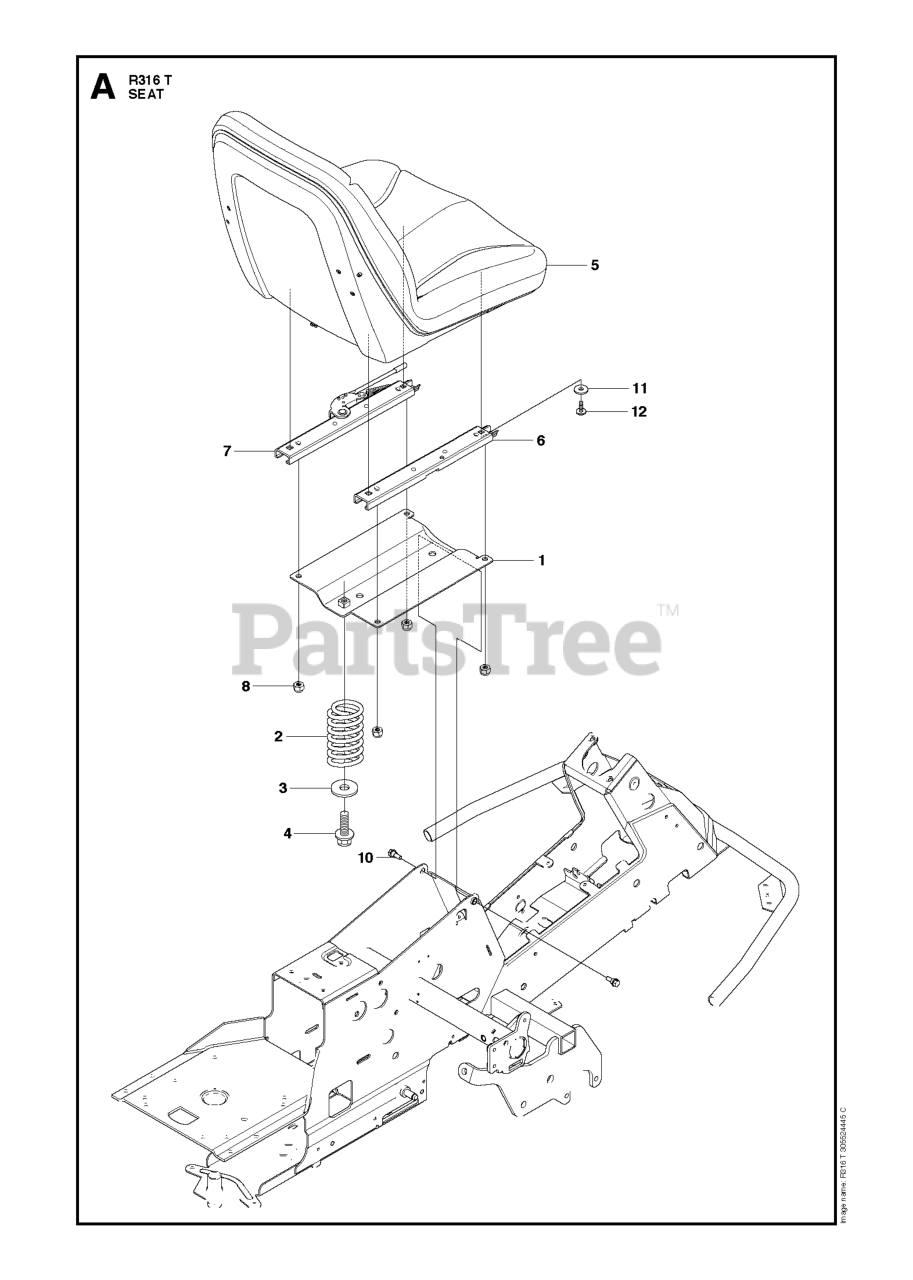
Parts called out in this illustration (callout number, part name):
1	SEAT BRACKET
2	SEAT SPRING
4	Screw M10x25
5	SEAT
8	LOCKNUT M8
11	WASHER
12	BOLT.FIN.HEX.5/16-18X3/4
